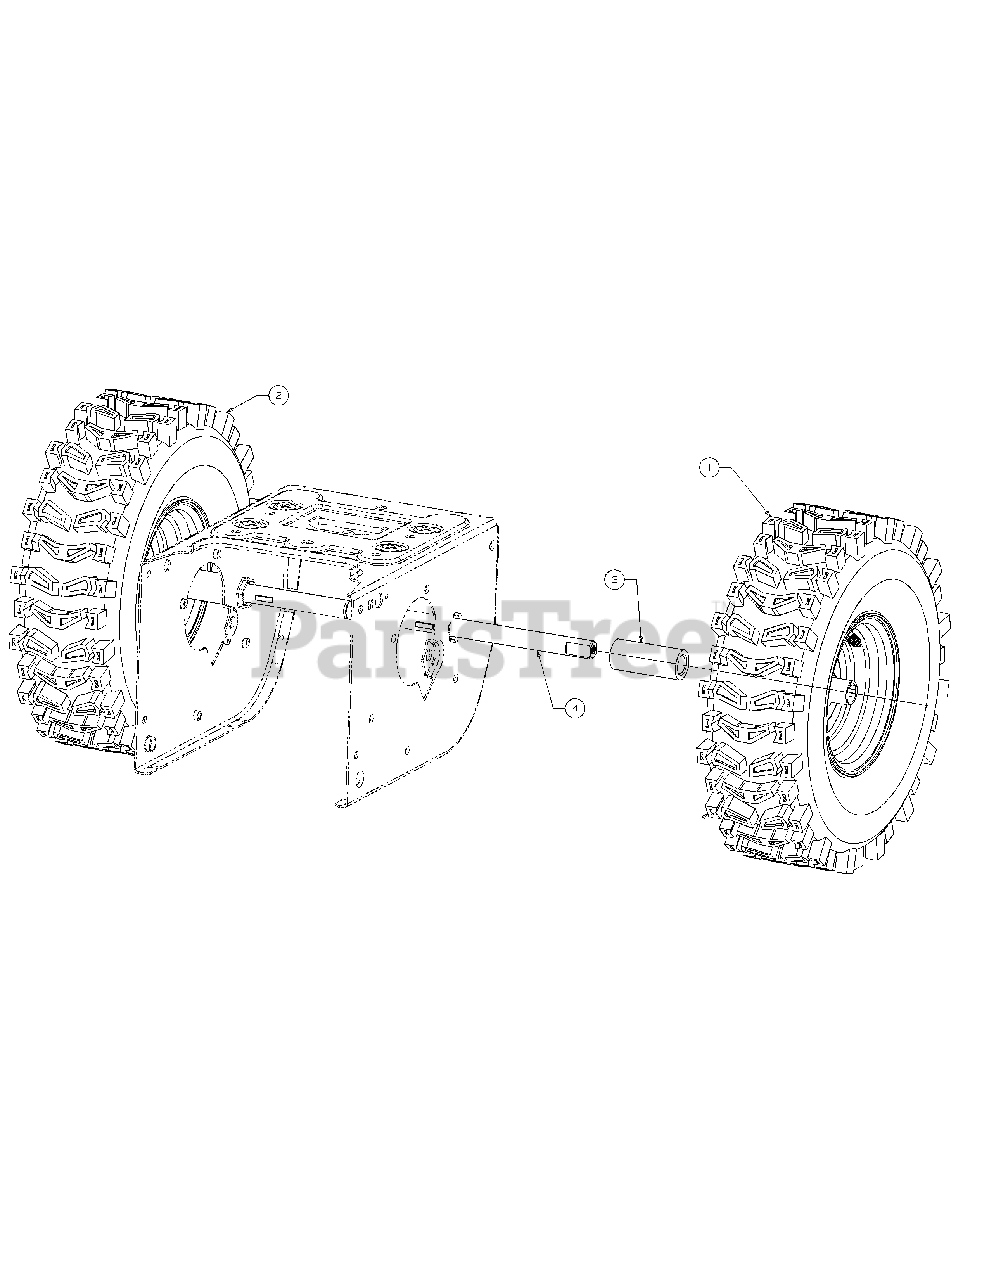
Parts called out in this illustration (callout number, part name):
1	Wheel Comp-LH
2	Wheel Comp-RH
3	Spacer-Wheel 1.25O
